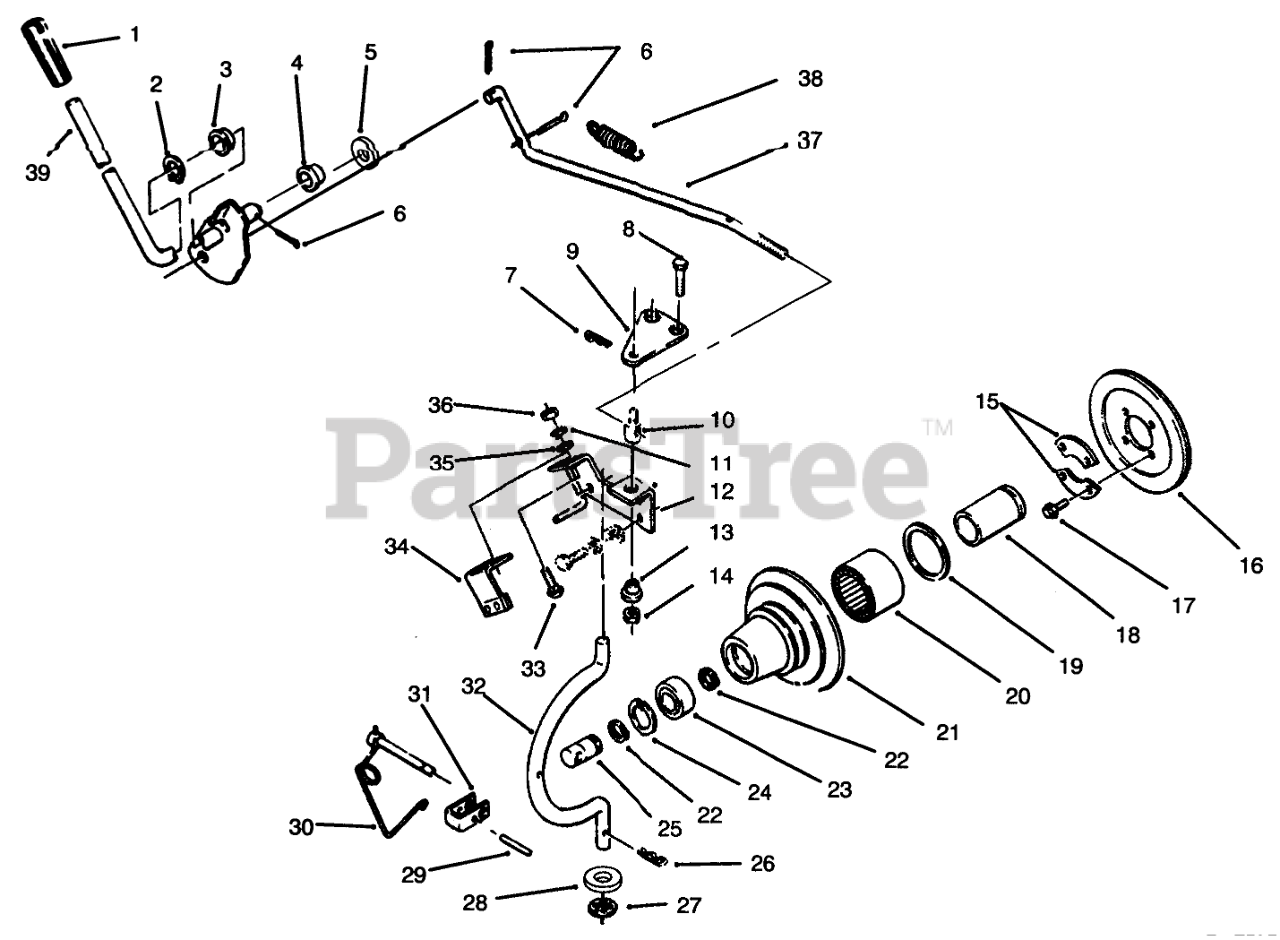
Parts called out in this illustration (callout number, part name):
1	GRIP
2	RING-EXT GRIP
3	BUSHING-NYLINER
4	NYLINER BUSHING
5	SHIM-WASHER
6	PIN-COTTER
7	PIN-HAIR
8	SCREW-HH
9	PLATE
10	TRUNNION
11	WASHER-LOCK
12	Bracket-Engine
13	SPACER-LIFT LINK
14	NUT-LOCK, NI
15	RETAINER
16	Facing-Clutch
17	SCREW-HEX HD CAP
18	RACE-BEARING
19	SEAL-OIL
20	Seal
21	Housing-Clutch
22	Ring-Snap
23	BEARING-BALL
24	RING-RETAINING
25	SHAFT-PTO
26	PIN-COTTER, HAIR
27	RING-REINFORCED CIRC
28	WASHER-FLAT
30	LOCKING PIN ASM
31	CLEVIS
32	ROD-HOUSING
33	SCREW-CARR
34	ASM-Bracket
35	WASHER-FLAT
36	NUT-JAM
37	ROD-PTO CLUTCH
38	SPRING
39	ASSY PTO CLUTCH LEVE
